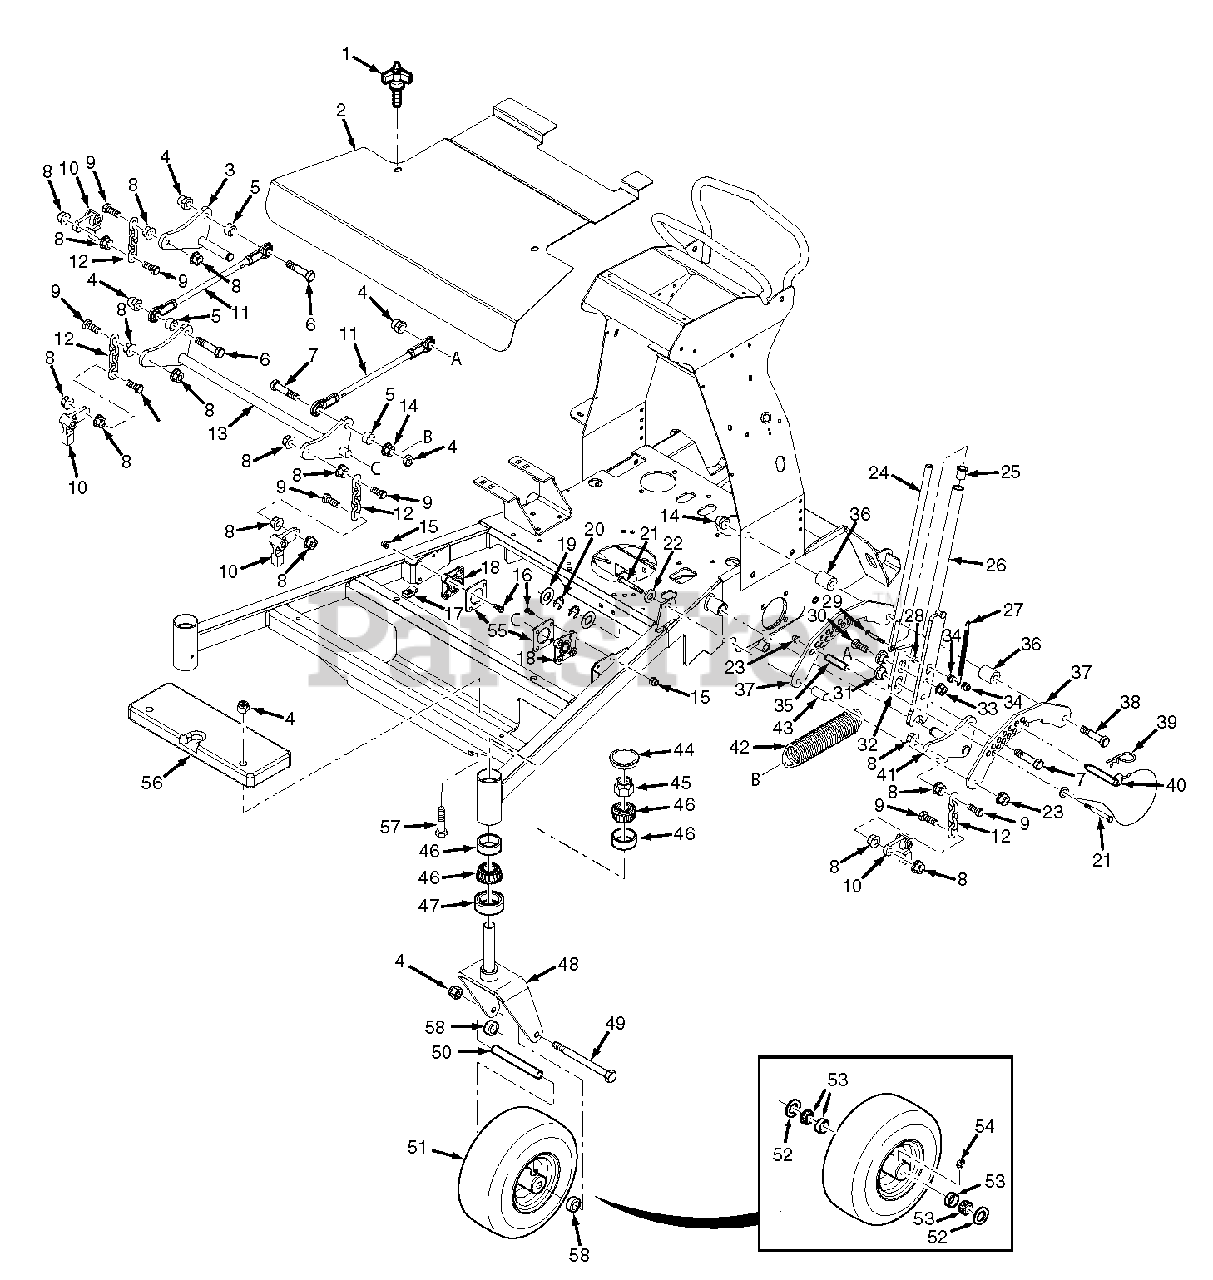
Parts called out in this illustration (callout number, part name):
1	Knob w/Stud
2	Belt Cover w/Decals (36A)
2	Belt Cover w/Decals (48V)
3	Arm Weldment, RH
4	Nut, Elastic Stop 1/2-13
5	Spacer
6	Bolt, Hex Head 1/2-13 x 2-1/2"
7	Bolt, Hex Head 1/2-13 x 3"
8	Nut, Serrated Flange 3/8-16
9	Bolt, Hex Head 3/8-16 x 1-1/2"
10	Lever, Deck Level
11	Linkage, Deck Lift (36A)
11	Linkage, Deck Lift (48V)
12	Chain
13	Deck Lift Weldment (36A)
13	Deck Lift Weldment (48V)
14	Nut, Serrated Flange 1/2-13
15	Nut, Elastic Stop 5/16-18
16	Bolt, Hex Head 5/16-18 x 1"
17	U-Nut, 3/8-16
18	Bearing, Deck Lift - 36A
18	Bearing, Deck Lift - 48V
19	Flatwasher, 3/4-.766 x 1.25 x .0598
20	Retaining Ring, .750 "E"
21	Bolt, Hex Head 3/8-16 x 3"
22	Flatwasher, 3/8-.391 x .938 x .105
23	Nut, Elastic Stop 3/8-16
24	Actuator Rod
25	Bearing
26	Handle Weldment, Deck Latch
27	Spring, Deck Latch
28	Spacer
29	Bolt, Hex Head 3/8-16 x 2-1/2"
30	Bolt, Hex Head 1/2-13 x 1-3/4"
31	Bushing, Deck Latch
32	Deck Latch, Outer
33	Nut, Serrated Flange 1/2-13
34	Nut, Elastic Stop 3/8-16
35	Spacer
36	Spacer (36)
36	Spacer (48 / 52)
37	Bracket, Deck Height
38	Bolt, Hex Head 1/2-13 x 4-1/2"
39	Hair Pin Cotter
40	Pin Assembly w/Lanyard
41	Arm Weldment, LH
42	Spring, Deck Lift
43	Spacer
44	Cap, Grease
45	Nut, Elastic Stop 1"-14
46	Bearing w/Race
47	Seal, 2" OD x 1.625 ID
48	Caster Yoke Weldment
49	Bolt, Hex Head 1/2-13 x 6-1/2"
50	Sleeve, Caster Wheel
51	Caster Wheel Assembly, 11 x 4.0-5
53	Bearing, Tapered Roller
54	Grease Fitting, 45 Degree
55	Reinforcement, Bearing - 48V
56	Weight
57	Bolt, Hex Head 1/2-13 x 2-3/4" (48V & 52V - One Weight)
57	Bolt, Hex Head 1/2-13 x 4-1/2" (36A - Two Weights)
57	Bolt, Hex Head 1/2-13 x 5-1/2" (Three Weights Installed)
58	Spacer, Caster Wheel
